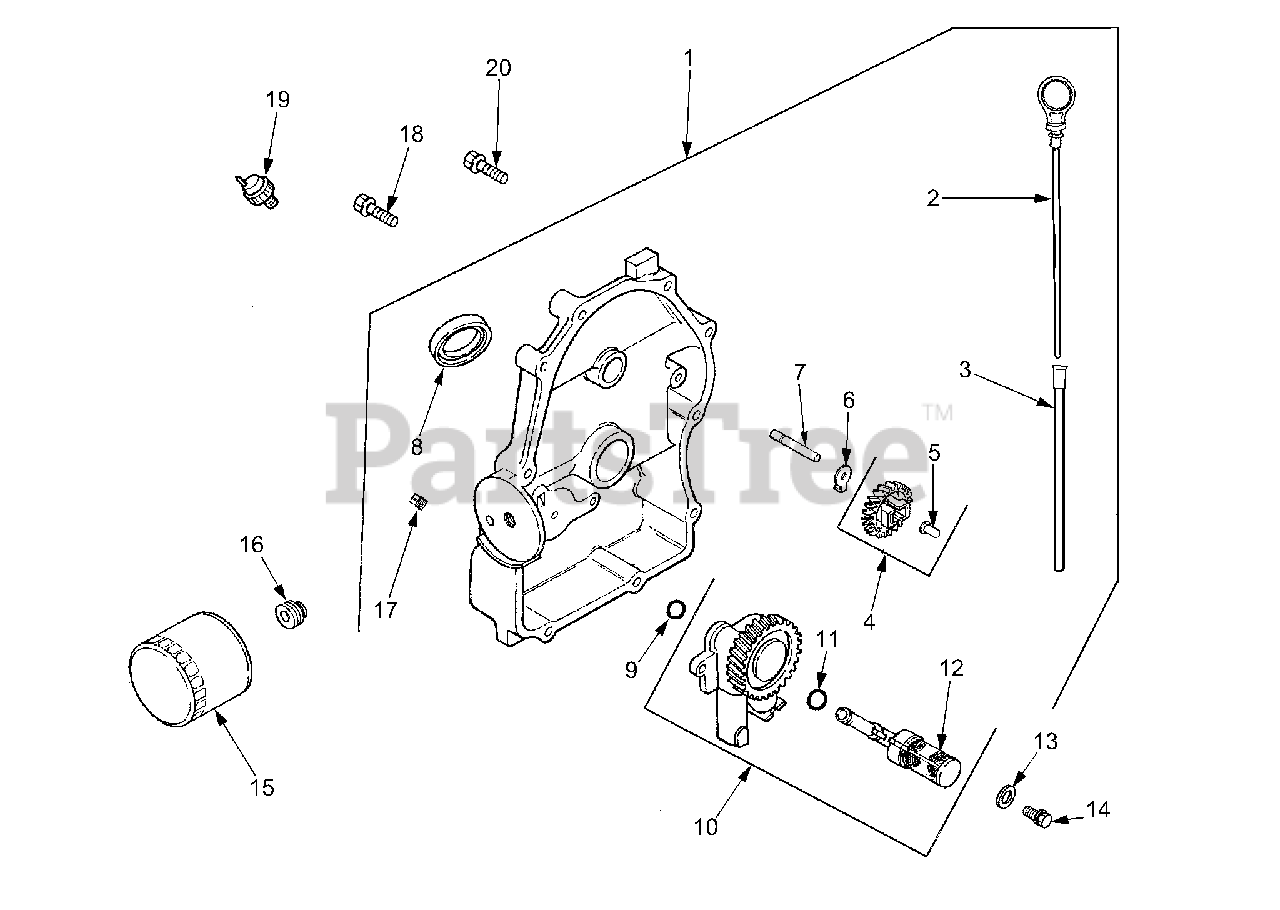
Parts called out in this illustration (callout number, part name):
1	Plate, Closure Assembly
3	Tube, Dipstick
4	Kit, Governor Gear
5	Pin, Governor Regulating
6	Tab, Locking
7	Shaft, Governor Gear
8	Seal, Oil (PTO End)
10	Oil Pump Assembly
11	O-Ring, Oil Pick-Up
12	Pick-Up, Oil
13	Washer, Plain
14	Screw, Hex Flange M6 x 1 x 25
15	Filter, Oil
16	Nipple, Oil Filter
17	Plug, Pipe 1/8"
18	Screw, Hex Flange M8 x 1.25 x 45
19	Switch, Pressure
20	Screw, Hex Flange M8 x 1.25 x 45
